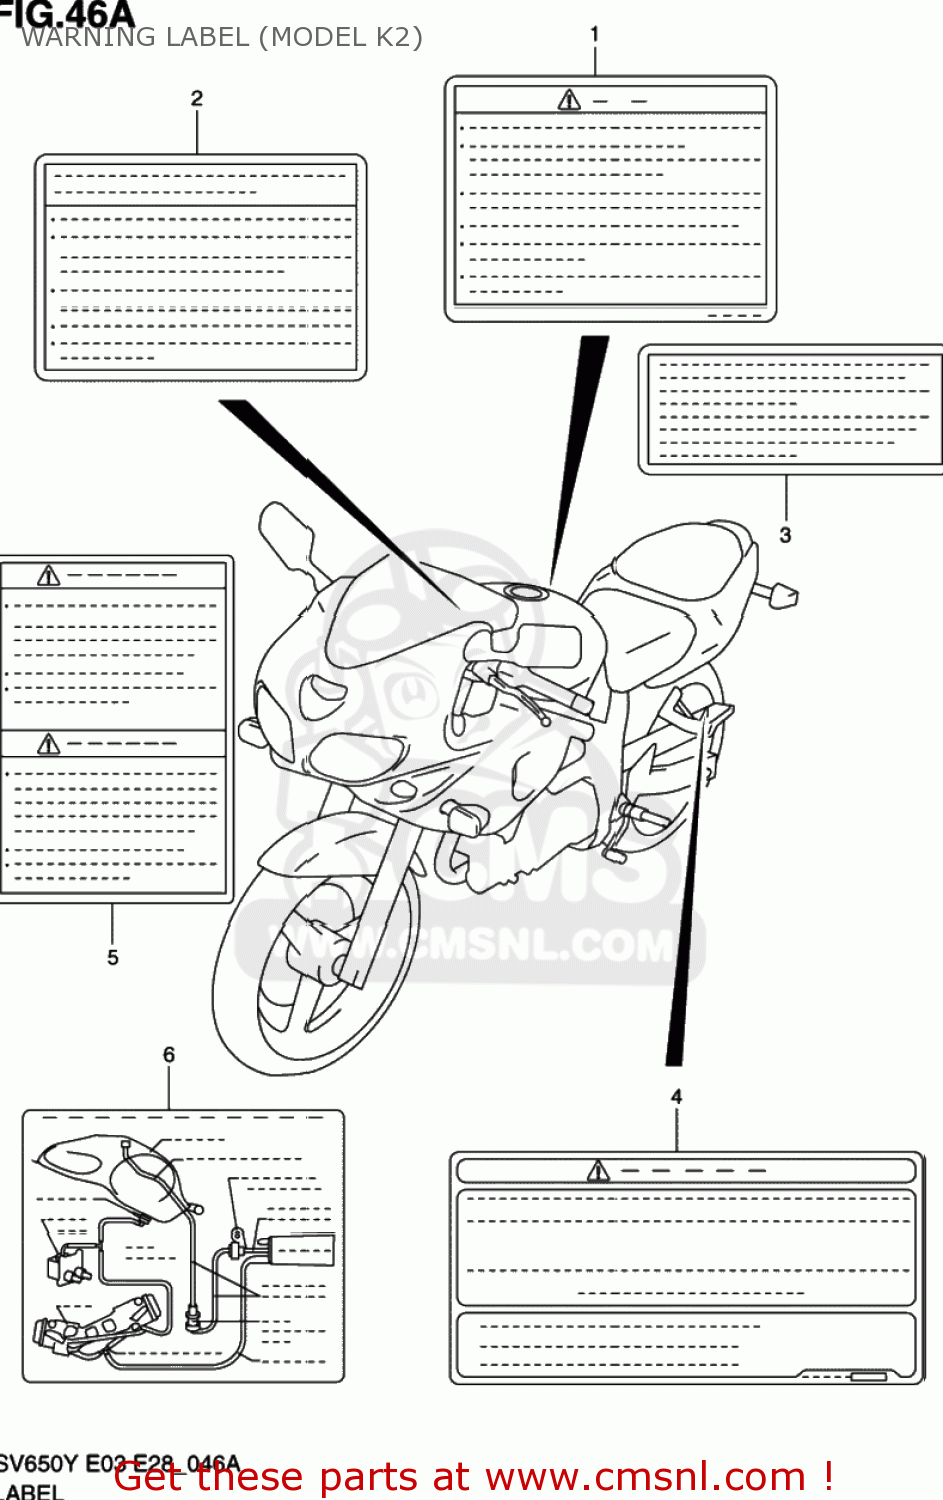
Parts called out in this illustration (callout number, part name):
1	LABEL,GENERAL WARNING
2	LABEL,SCREEN
3	LABEL,MANUAL NOTICE
4	STICKER
5	LABEL,WARNING STEERING
6	LABEL,VACUUM HOSE ROUTING
7	MANUAL,OWNER'S
